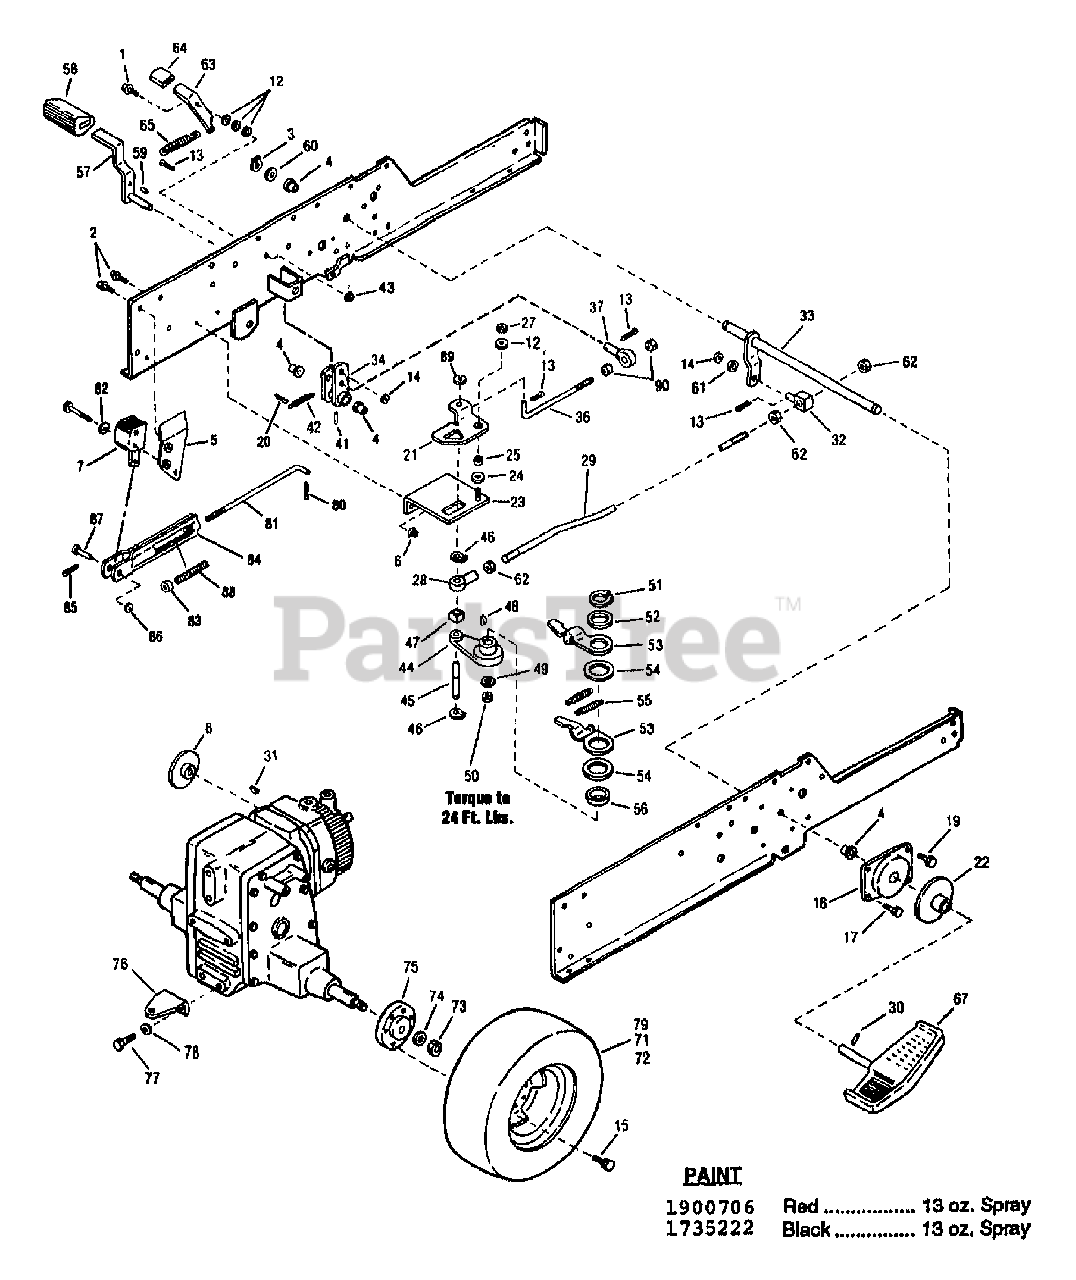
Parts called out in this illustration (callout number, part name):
1	SCR-HFLK 3/8-16X1.00 ZP
3	RING-RETAIN .625 ID
4	BEARING-FLANGE
5	BRKT-TRANS SUPPORT
6	NUT-HFLK 3/8-16 ZP
7	KIT-BRAKE
8	DISC-BRAKE {13062}
8	DISC-BRAKE {13060}
12	WASHER-FLAT 3/8 SAE
13	PIN-COTTER .09X.75 ZP
14	WASHER-FLAT 5/16 SAE
15	BOLT-HUB
18	CLUTCH
19	SCR-SEMS MACH
20	PIN-COTTER .120X1.00 ZP
21	PLATE-NEUTRAL
22	ASSM-CONTROL DISC
23	PLATE-NEUTRAL
24	WASHER-1.75X.39X.059
25	SPACER-.625X.4X.2
27	NUT-H/LK 3/8-16
28	ROD-END
29	ROD-SPEED CONTROL
30	PIN-ROLL
31	KEY-WOODRUFF .188X.75
32	SWIVEL
33	SHAFT-SPEED CONTROL
36	ROD-BRAKE CONTROL
37	SWIVEL
41	PIN-DRIVE .187X1.0
43	NUT-LOCK 3/8-16
44	ARM-SPEED CONTROL
45	PIN-CONTROL
46	RING-RET.EXT .437 ID
48	KEY-WOODRUFF 1/8 X 5/8
49	WASHER-1.06X.531X.1 ZP
50	NUT-H/LK 1/2-13
51	RING-RET
52	WASHER
54	WASHER-THRUST
55	SPRING
56	BEARING
57	PEDAL-BRAKE
58	FOOT REST
59	PIN-ROLL .188X.75
60	WASHER-1.115X.637X.06
61	WASHER-.632X.39X.0329
62	NUT-HEX/JAM 7/16-20
63	LOCK-BRAKE
64	GRIP {13060}
64	GRIP {13062}
65	SPRING
67	PEDAL-FOOT
71	TIRE-23X10.5X12
72	STEM-VALVE
73	NUT-H/LK 3/4-10
74	SPACER-1.812X.765X.179
75	HUB-WHEEL {13060}
75	HUB-WHEEL {13062}
76	HITCH-DRAWBAR
77	SCR-HH 1/2-13X1.25 G5 ZP
78	WASHER-LK .5
79	RIM-WHEEL REAR
80	PIN-COTTER .125 X .75 ZP
81	ROD-BRAKE
82	WASHER-LK .375 @ DEPL
83	NUT-SPECIAL
84	SPRING-YOKE ASSM
85	PIN-COTTER
86	WASHER-FLAT 1/4 SAE
87	PIN-CLEVIS .25X.62
88	SPRING-COMPRESSION
90	NUT-HEX JAM 5/16-18
